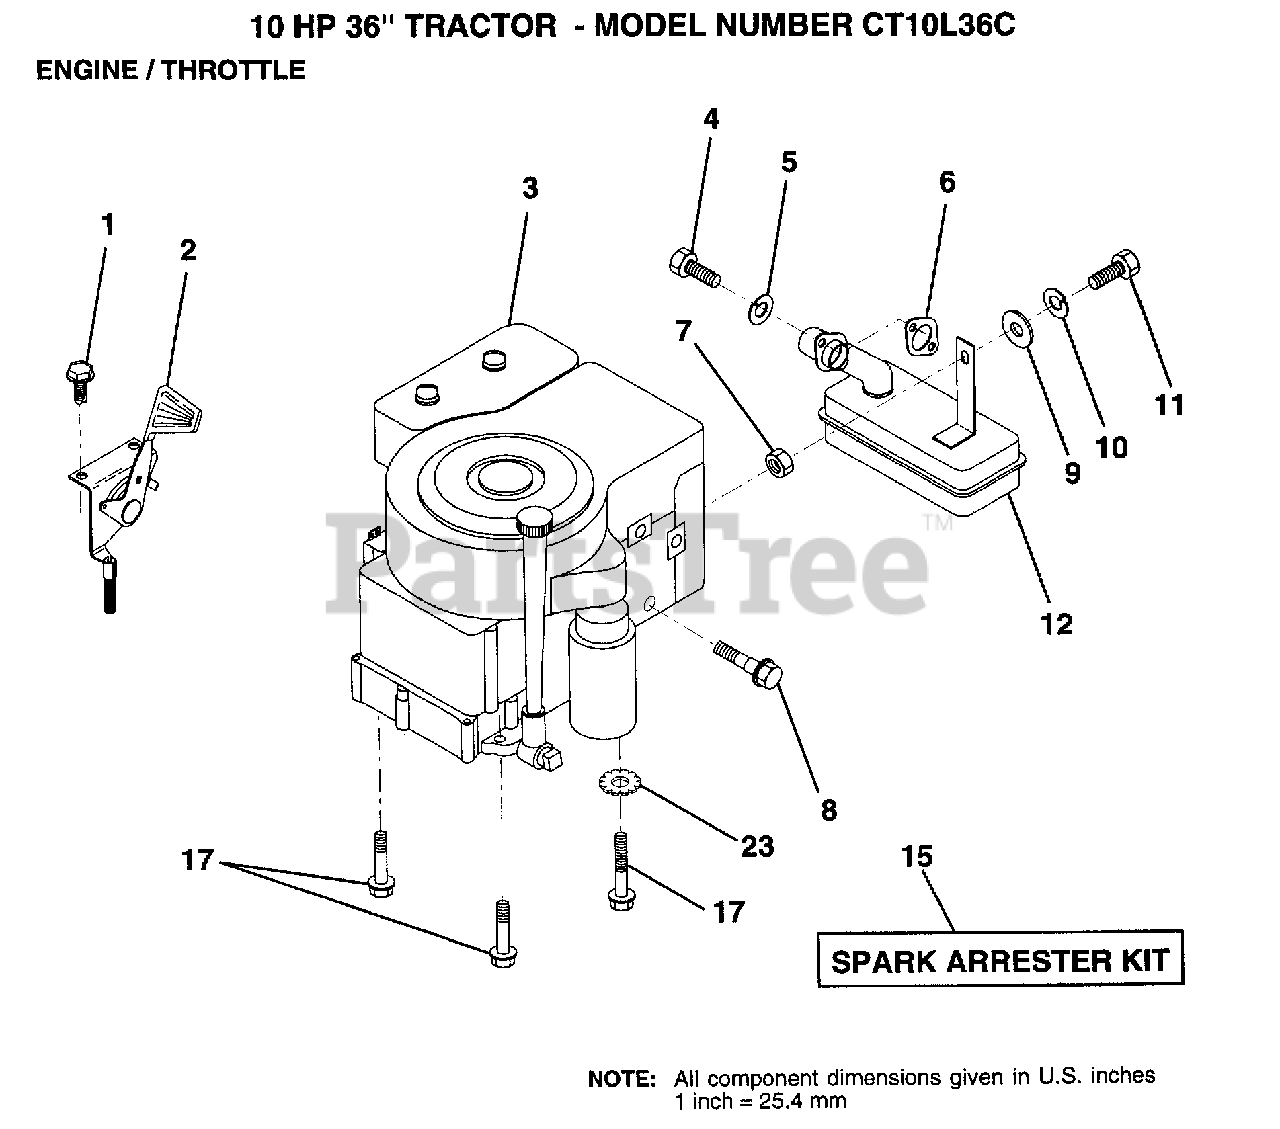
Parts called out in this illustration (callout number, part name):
1	SCREW.1/4-20X1/2
2	"CONTROL,THROTTLE"
3	ENGINE, B&S 10HP
4	SCREW
5	LOCKWASHER
7	NUT.HEX.5/16-18
8	BOLT T
10	LOCKWASHER
12	MUFFLER
17	SCREW LT
23	LOCKWASHER
